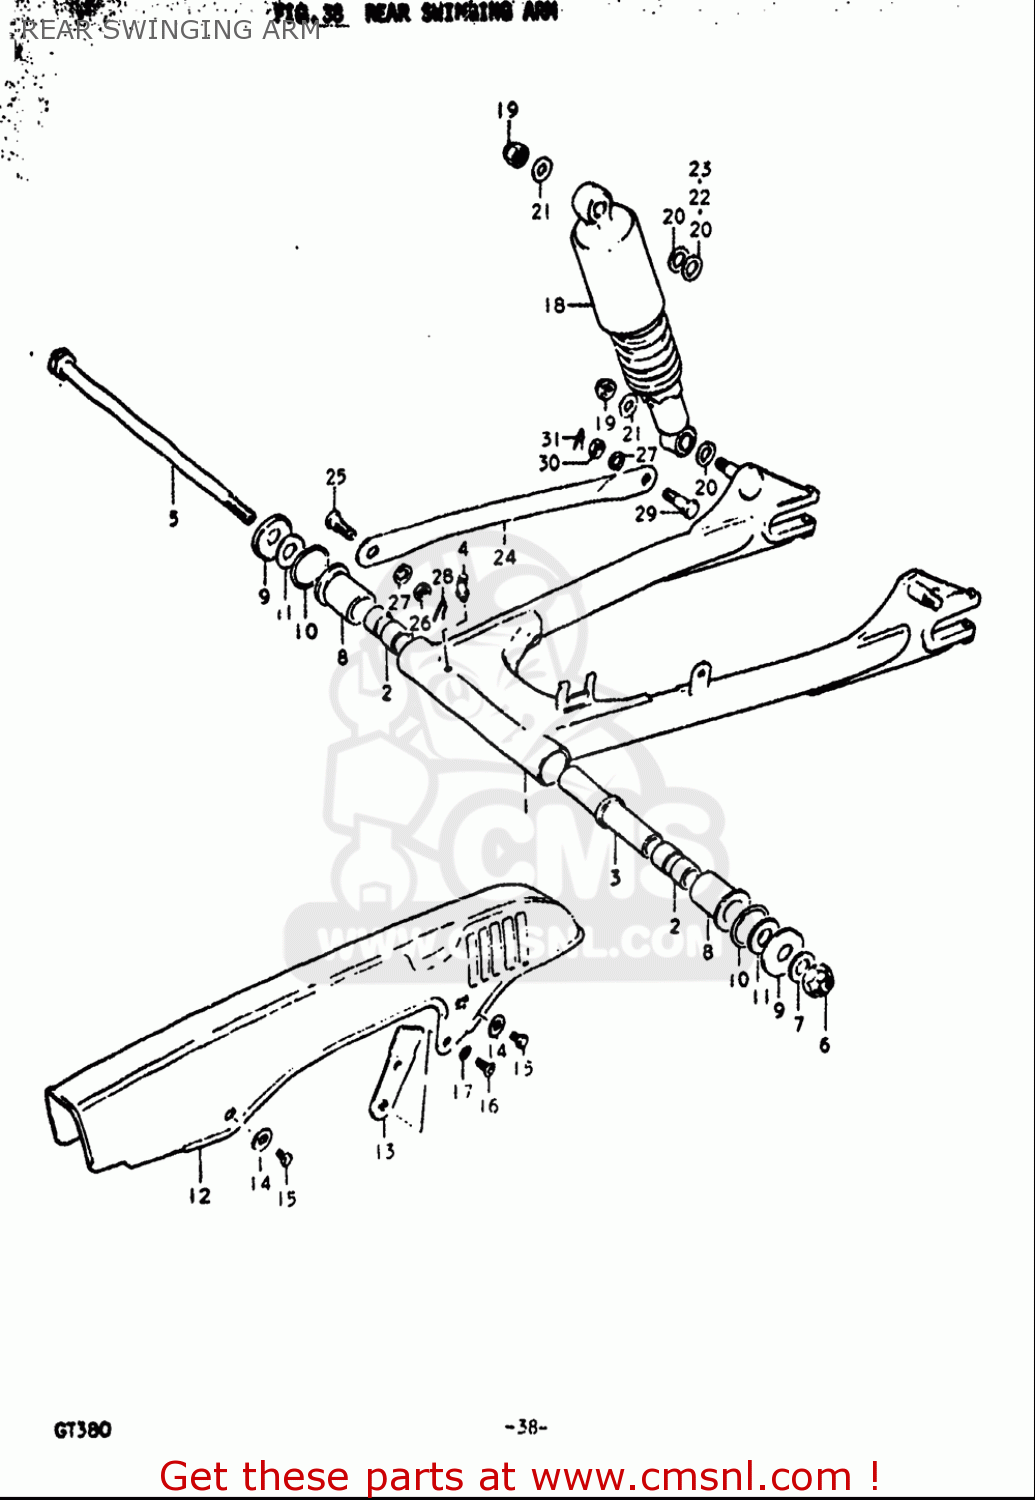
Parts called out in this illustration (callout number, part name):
2	BUSH
4	NIPPLE,GREASE
5	SHAFT,REAR SWING ARM
7	WASHER
8	SPACER
9	COVER
10	O RING(D:3,ID:29.5)
11	WASHER(14.5X29X2.3)
14	WASHER
15	BOLT(6X8)
16	SCREW
17	LOCK WASHER
19	NUT
20	WASHER
21	WASHER(19X32X1)
22	WASHER(12.5X24X3.2)
23	WASHER(12.5X24X1.6)
26	NUT
27	WASHER,LOCK
28	CLIP
29	BOLT(10X31)
30	NUT
31	SPRING,RETAINER
